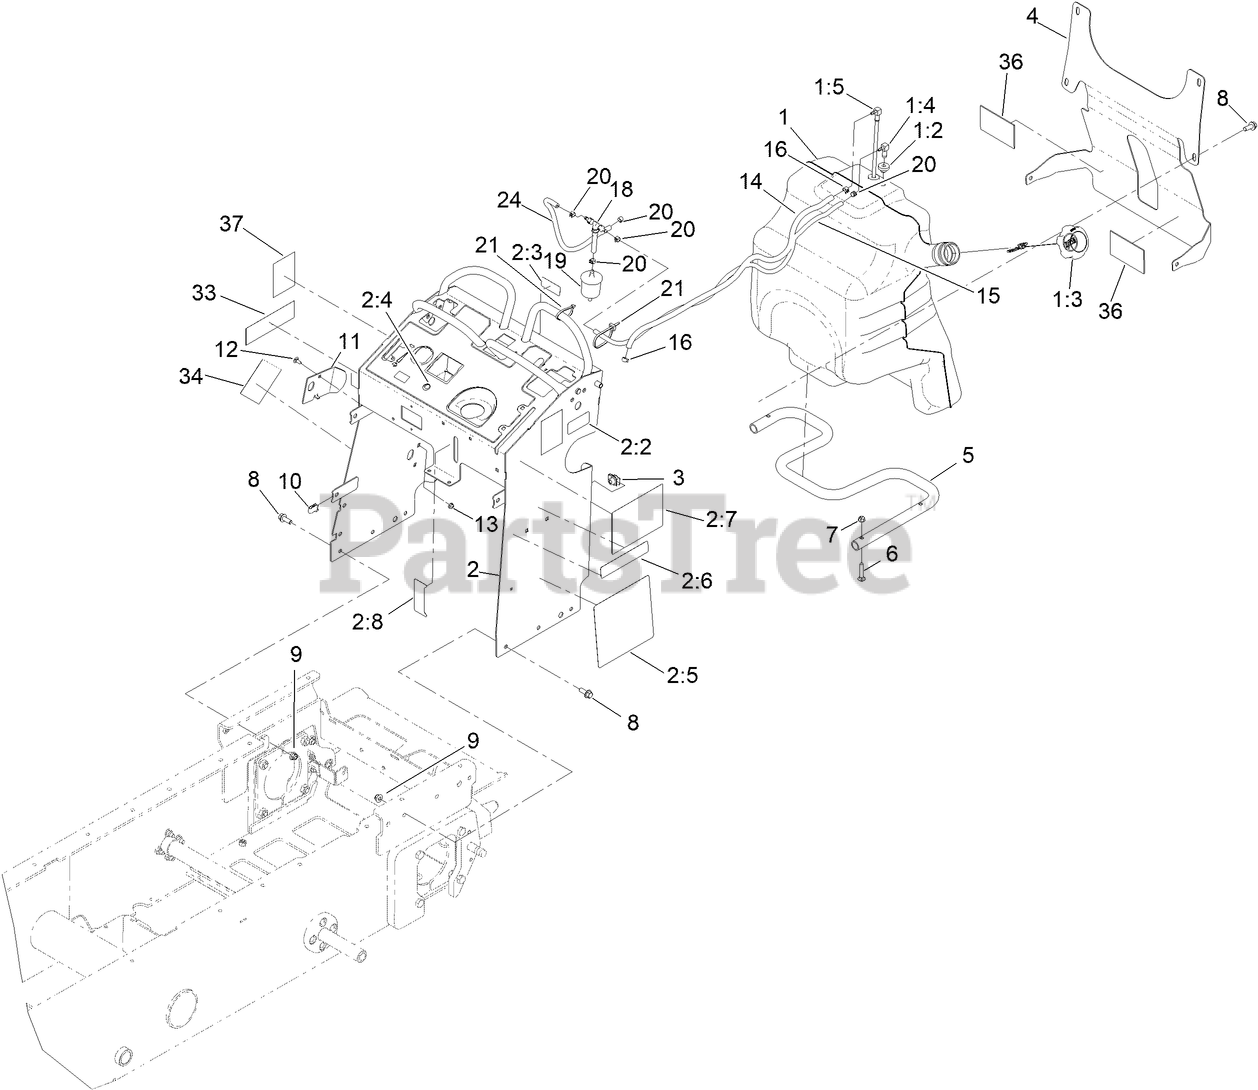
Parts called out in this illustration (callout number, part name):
1	FUEL TANK ASM
1:2	BUSHING
1:3	CAP-FUEL
1:4	FITTING-ELBOW, 90 DEG
1:5	ASM, TUBE-FUEL
2	TOWER ASM
2:2	DECAL-FILL, FUEL
2:3	DECAL-FUSE
2:4	DECAL-CONTROL PANEL
2:5	DECAL-SERVICE, 2500-T
2:6	DECAL- 2500-T
2:7	DECAL-SRVSW5X7
2:8	DECAL-LEVEL, OIL
3	NUT-TINNERMAN
4	BRACKET-CROSS
5	TUBE-FUEL TANK MOUNT
6	BOLT-CAR
7	NUT-HF, NI
8	SCREW-HHF
9	NUT-HF, NI
10	NUT-CLIP, U
11	PLATE-STRIKER
12	SCREW-CARR
13	NUT-HF
14	HOSE-FUEL
15	HOSE-FUEL
16	CLAMP-HOSE
18	TEE AND CHECK
19	FILTER-FUEL
20	CLAMP-HOSE
21	TIE-CABLE
24	HOSE-VENT
33	DECAL-CPER0014
34	DECAL-CPER0017
36	PAD-FOAM
37	DECAL- RHVSG3X4
